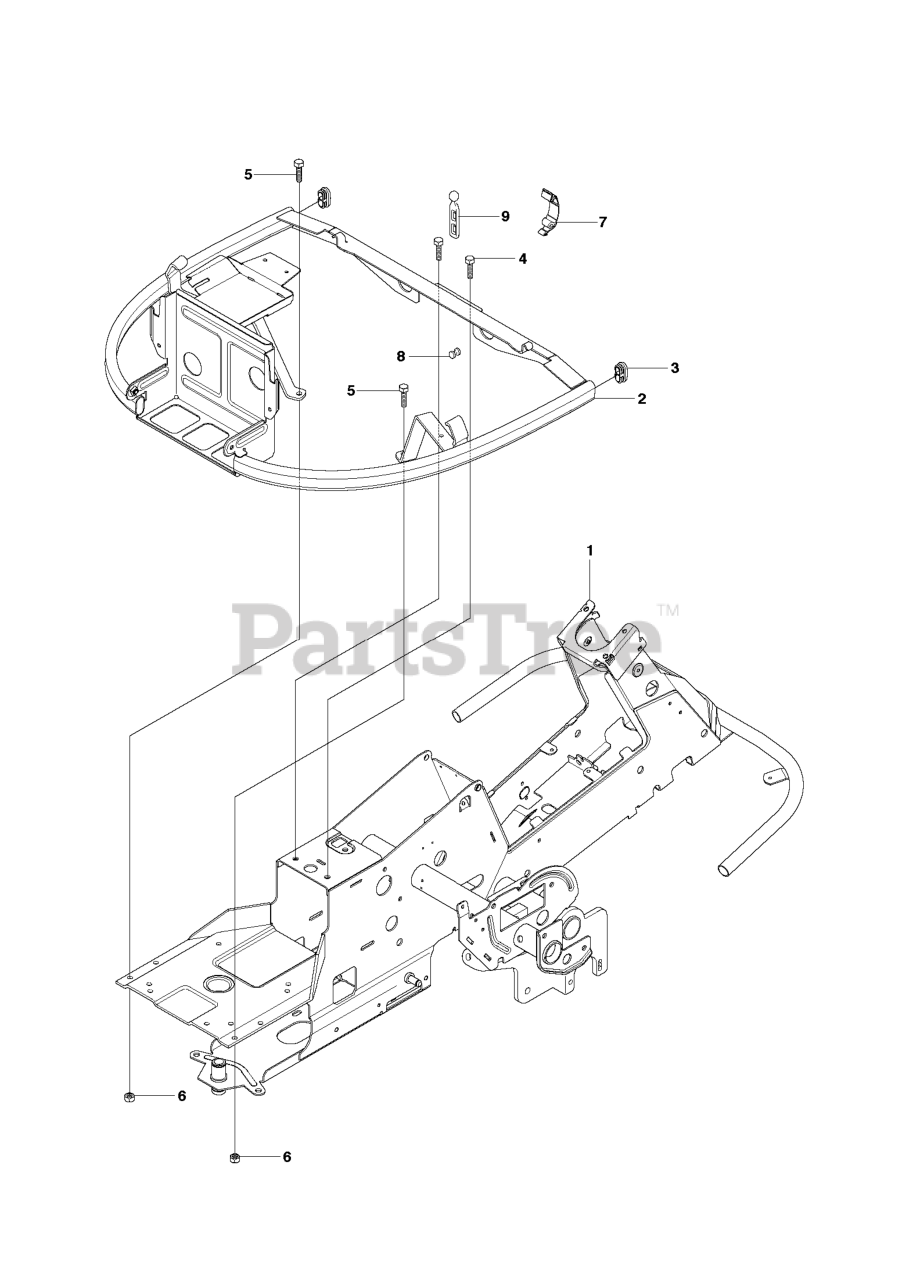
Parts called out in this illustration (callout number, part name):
6	LOCKNUT M8
7	CLIP GRAY
9	Support Strap
